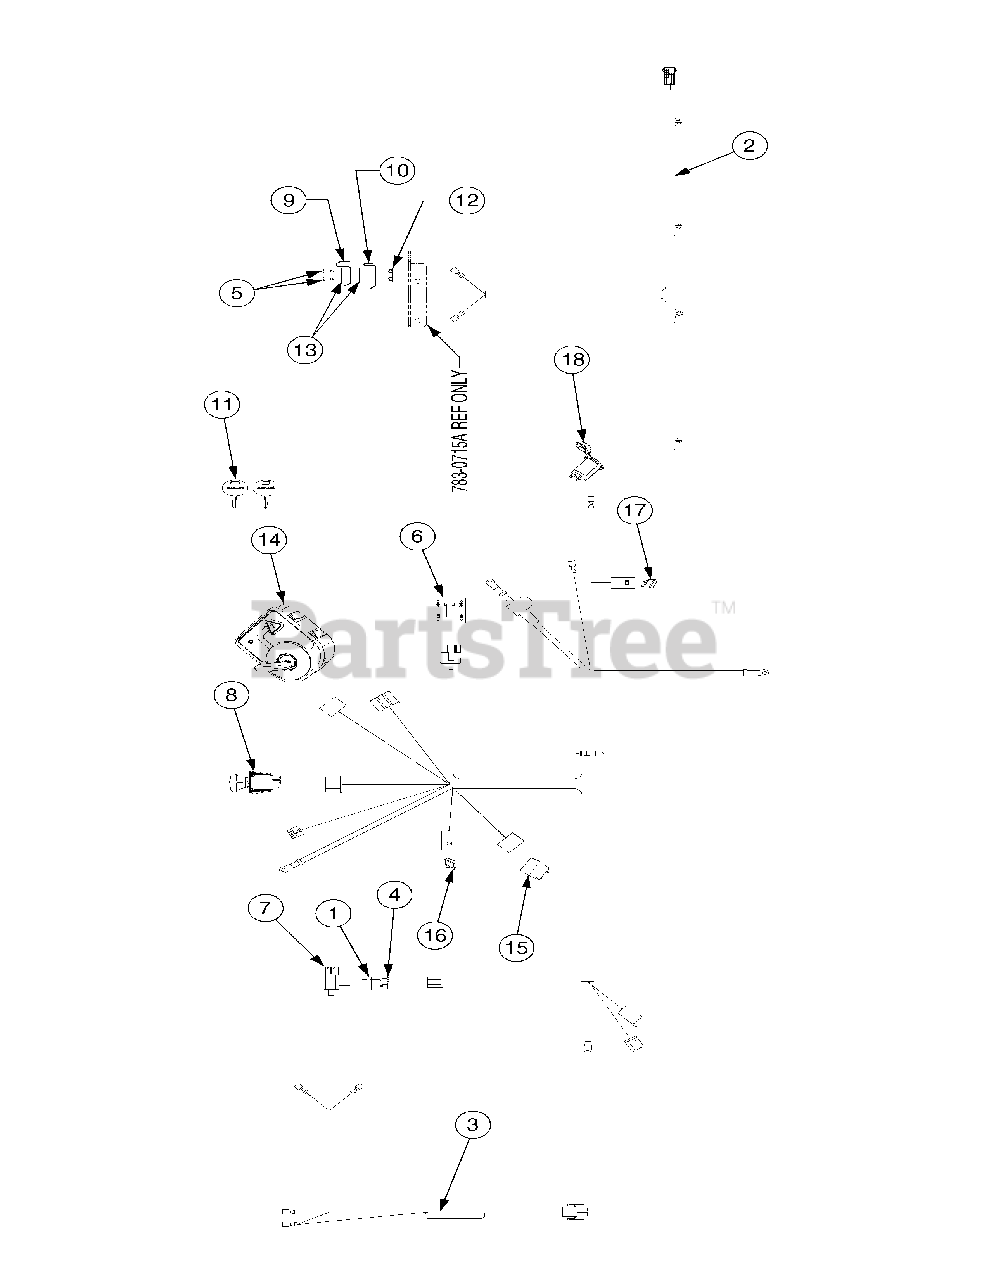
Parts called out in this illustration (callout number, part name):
1	Plate, Switch
2	Harness Assembly
3	Harness Assembly, Headlight
4	Screw, Hx. Wash. Hd. Tapp, 10-16 x .5
5	Screw, Hx. Wash. Hd. Tapp, 8-18 x .5
6	Indicator/ Meter Hour
7	Switch, Interlock
8	Switch, Electric PTO, Yellow Knob
9	Switch, Outer Seat Spring
10	Switch, Inner Seat Spring
11	Key, Switch, Plastic
12	Plate, Insulator Boss
13	Plate, Insulator
14	Switch, Key/Module
15	Relay
16	Fuse, 20 Amp
17	Fuse, 5 Amp
18	Receptacle, Power 12V
